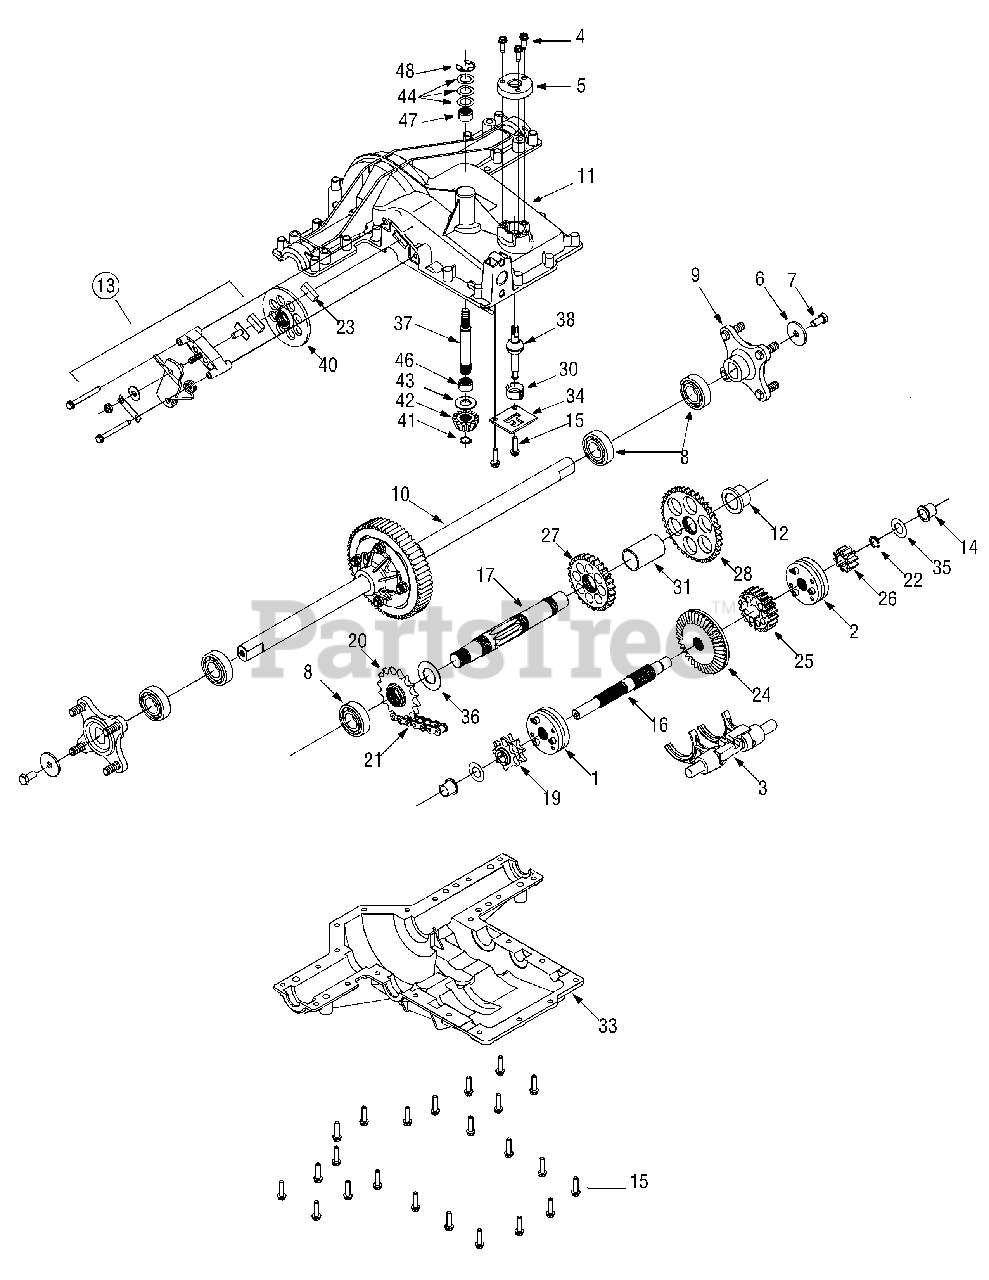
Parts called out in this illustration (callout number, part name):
1	Reverse Collar Assembly
2	Hi-Lo Collar Assembly
3	Shift Fork Assembly
4	Self-tapping Screw, 1/4-20 x .75
5	Shift Cover
6	Flat Washer
7	Lock bolt 3/8-16 x 0.75
8	Ball Bearing
9	Wheel Hub Assembly
10	Differential Axle Assembly
11	Upper Housing
12	Flanged Bearing
13	Brake Assembly
14	Flanged Bearing
15	Screw 1/4-20 x 1.0
16	Drive Shaft
17	Output Shaft
19	9-tooth Sprocket
20	16-tooth Sprocket
21	22-link Chain, .625
22	External Snap Ring
23	Brake Pad
24	41-tooth Bevel Gear
25	20-tooth Spur Gear
26	10-tooth Spur Gear
27	27-tooth Spur Gear
28	37-tooth Spur Gear
30	Shifter Insert
31	Shifter Cover
33	Lower Housing
34	Lockout Plate
35	Flat Washer, 5/8 x 1.0
36	Flat Washer, 1.01 x 1.86 x .060
37	Input Shaft
38	Shift Lever
40	Disc Brake
41	Retaining Ring, .56
42	13-tooth Bevel Gear
43	Flat Washer
44	Flat Washer, 5/8 x 1.0 x .030
44	Flat Washer, 5/8 x 1.0 x ..040
44	Falt Washer, 5/8 x 1.0 x .020
46	Needle Bearing
47	Needle Bearing
48	E-ring, .75
